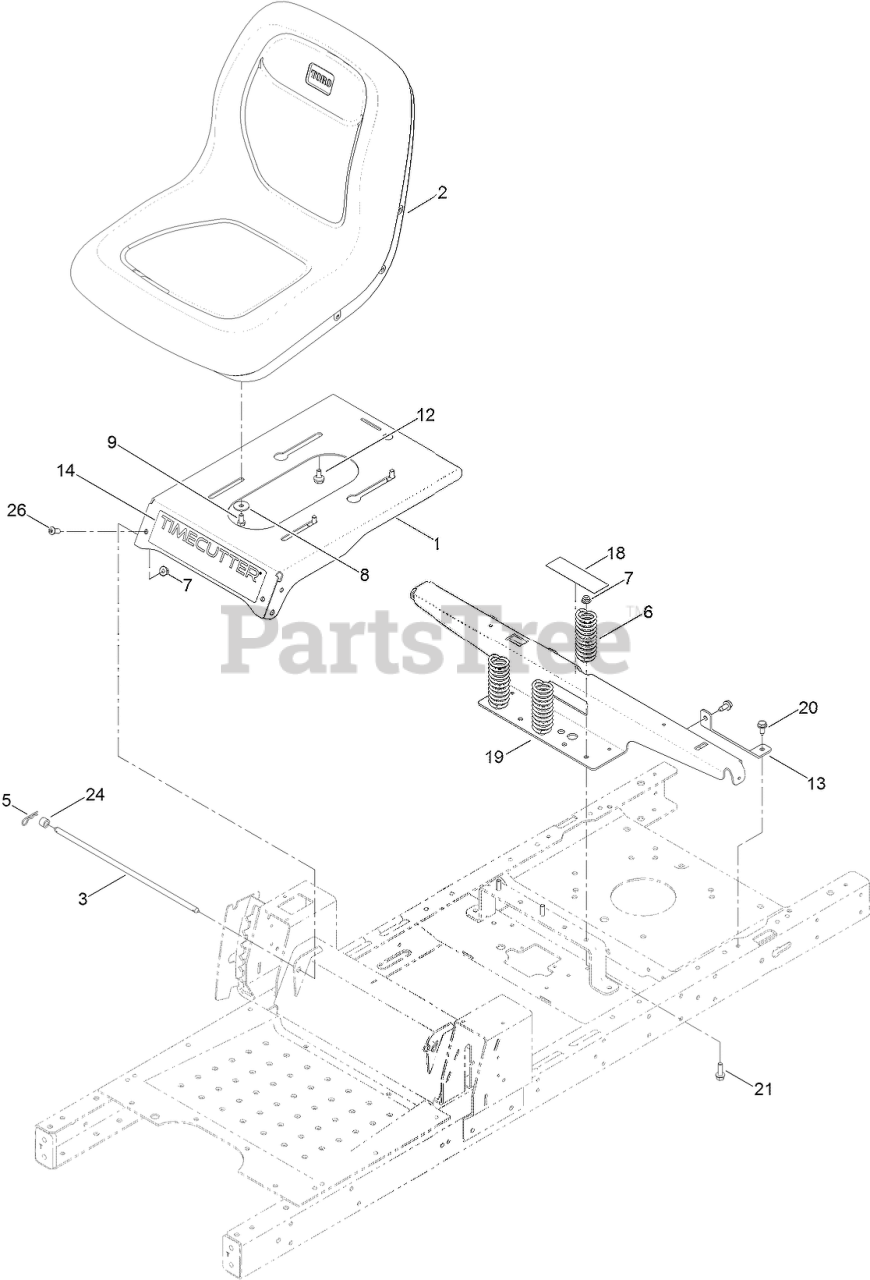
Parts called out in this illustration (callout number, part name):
1	PAN-SEAT
2	SEAT-18 INCH
3	ROD-STOP
5	PIN-COTTER
6	SPRING-COMPRESSION
7	NUT-HF, NI
8	WASHER-PIVOT
9	SCREW-HH
12	BOLT-SHOULDER
13	SUPPORT-TANK, REAR
14	DECAL-TIMECUTTER
18	DECAL-SERVICE, CE
19	SUPPORT-POD, WIDE
20	SCREW-HWHTF
21	SCREW-HHF
24	BUSHING-LEVER, LIFT
26	SCREW-HSBH
